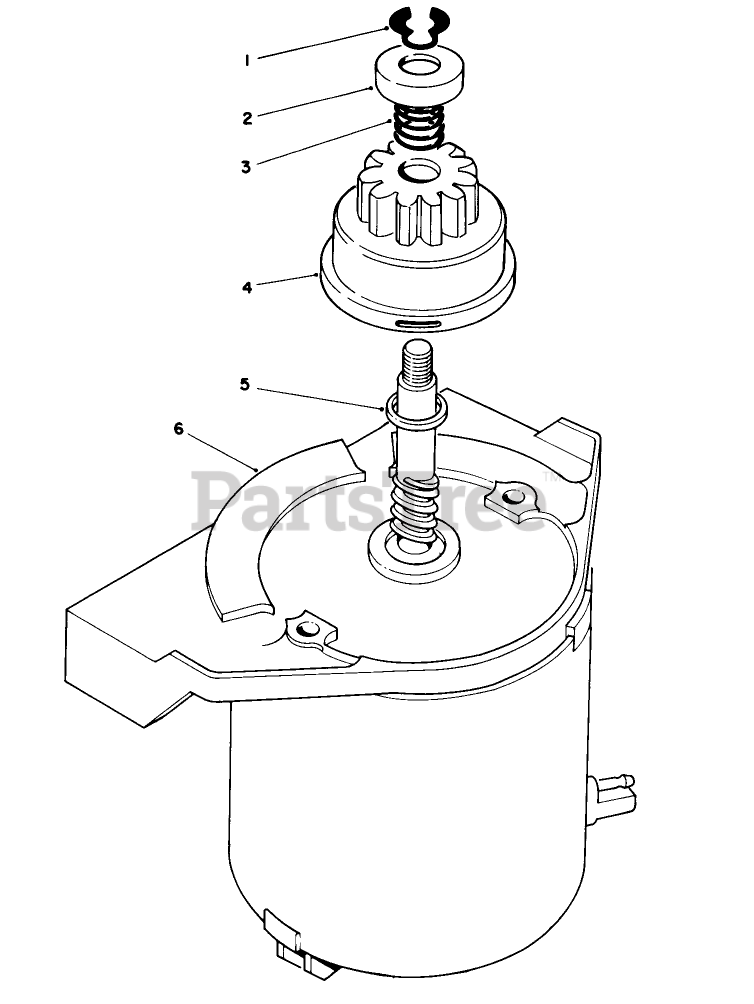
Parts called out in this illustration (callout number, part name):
1	RING-RETAINING
2	PINION STOP
3	COMPRESSION SPRING
4	PINION ASM
5	SPACER
6	END FRAME ASSY, MOTOR
